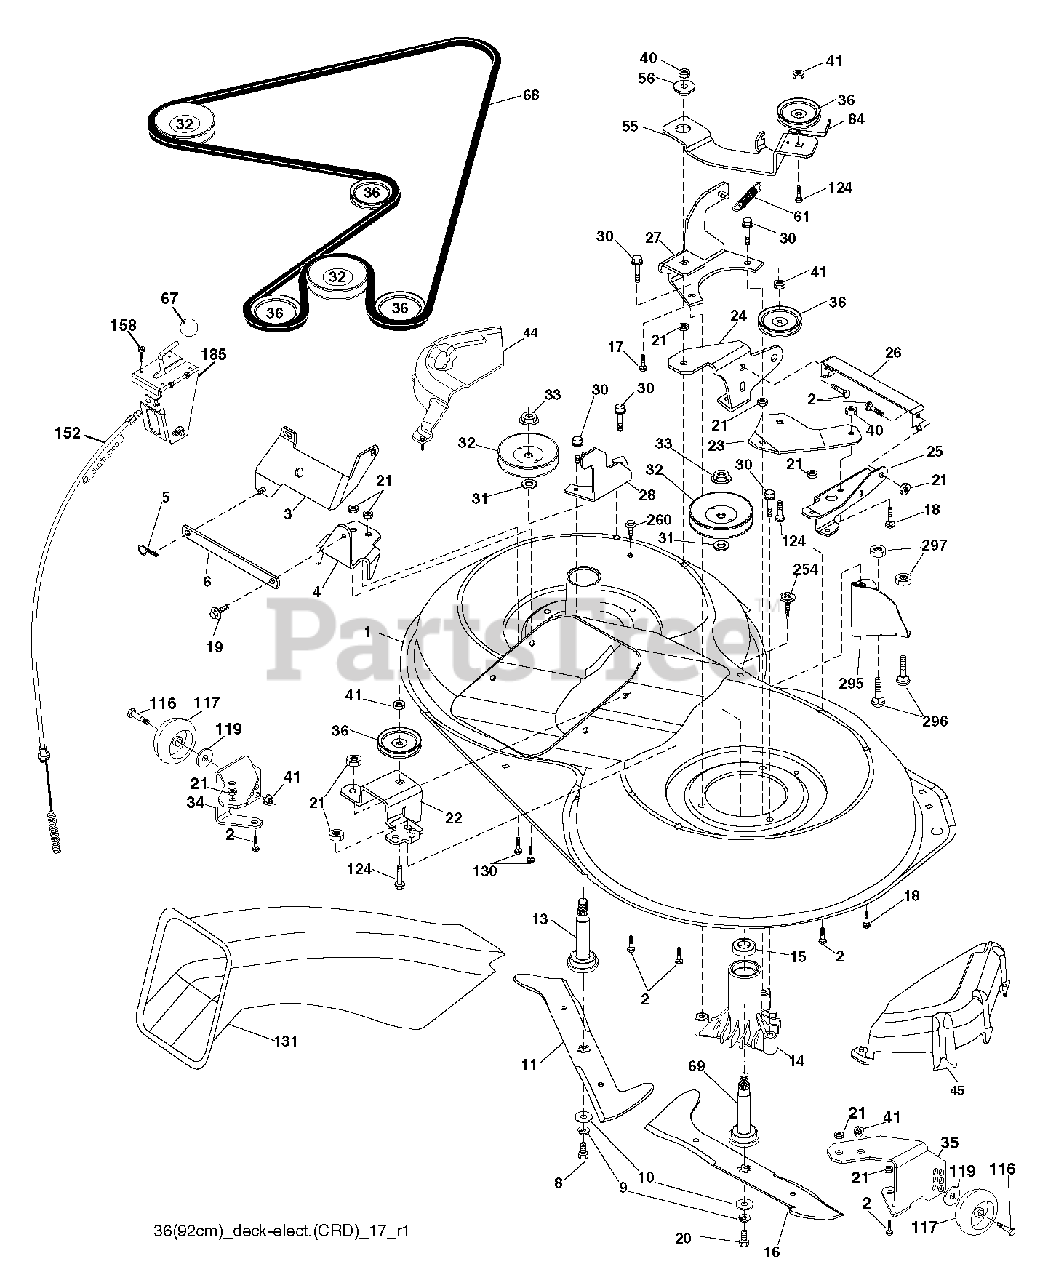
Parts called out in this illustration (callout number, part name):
2	BOLT
3	BRACKET.ASM.BAR.SWAY.CHASS
5	RETAINER-SPRNG RB
6	BAR SWAY
9	LOCKWASHER
10	WASHER.BLADE
13	SHAFT ASM VENT
14	HSG MANDREL
17	BOLT.3/8-14X1.25
19	BOLT SHD 5/16-18
21	LOCKNUT
22	BRACKET.SUPT.IDLER.REAR.RH
24	BRACKET
25	BRACKET
28	BRACKET
30	SCREW, WASHER HEAD
31	WASHER.SPACER.MANDREL
32	PULLEY MANDREL
33	NUT.FLANGE.LOCK.TOP
36	PULLEY.IDLER.4.25
40	LOCKNUT
41	NUT LOCK FLG 3/8-16 UNC
56	SPACER.RETAINER.MOWER
67	KNOB T (3/8 HOLE)
69	SHAFT.ASM.W/LWR.BRG.RH.THREAD
84	KEEPER, BELT IDLER
116	BOLT.SHOULDER.3/8-16X3-5/8
117	WHEEL. GUAGE RALLY
124	BOLT.3/8-16X1.50
131	CHUTE BAGGER
158	SCREW
185	HEAD ASM. CABLE CLUTCH
254	SCREW 3/8-16X1
260	SCREW 3/8-16X1/2
296	BOLT
297	NUT CENTERLOCK
